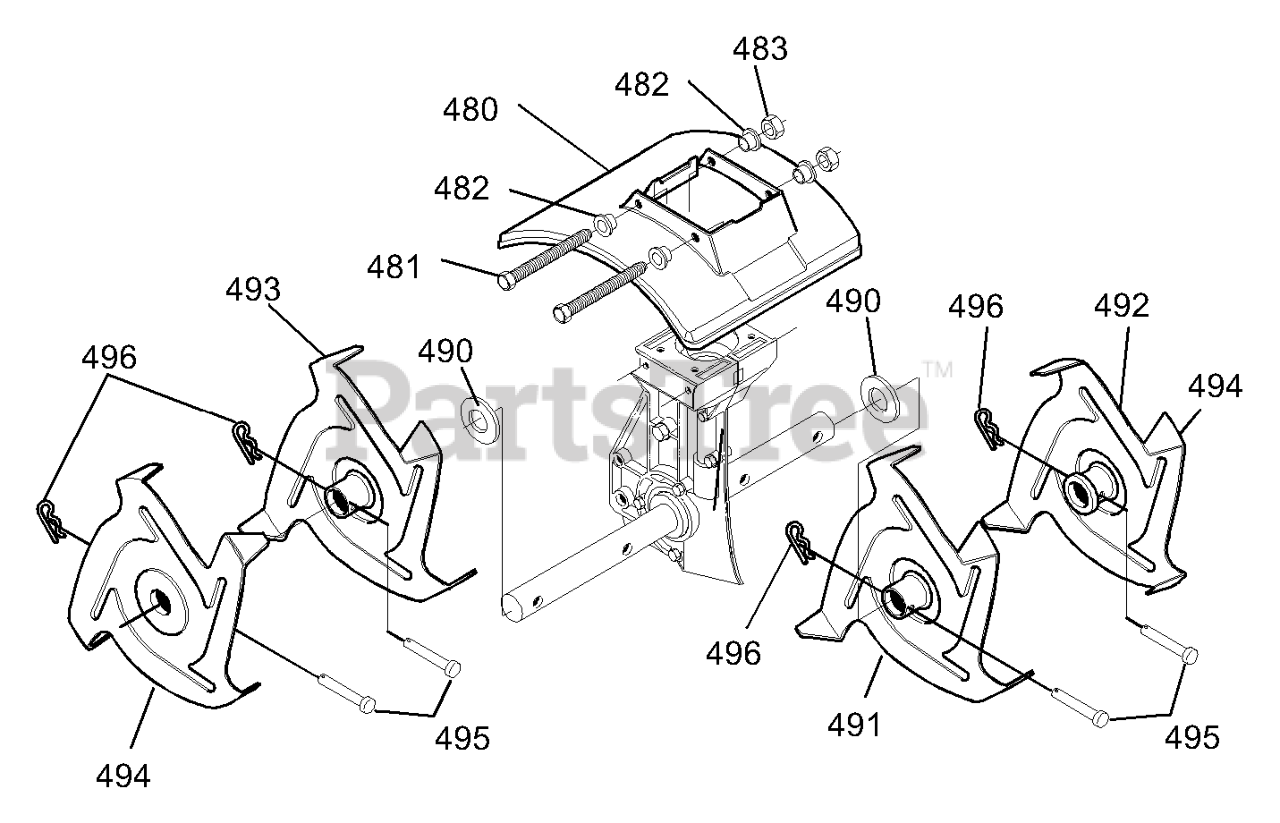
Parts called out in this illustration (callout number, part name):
480	Shield, Tine
481	Screw, 1/4-20x5.50
482	Spacer, Flange
483	Nut, 1/4-20
490	Washer, Felt
491	Tine Assy. Inner LH
492	Tine Assy. Outer LH
493	Tine Assy. Inner RH
494	Tine Assy. Outer RH
495	Clevis Pin
496	Hair Pin
